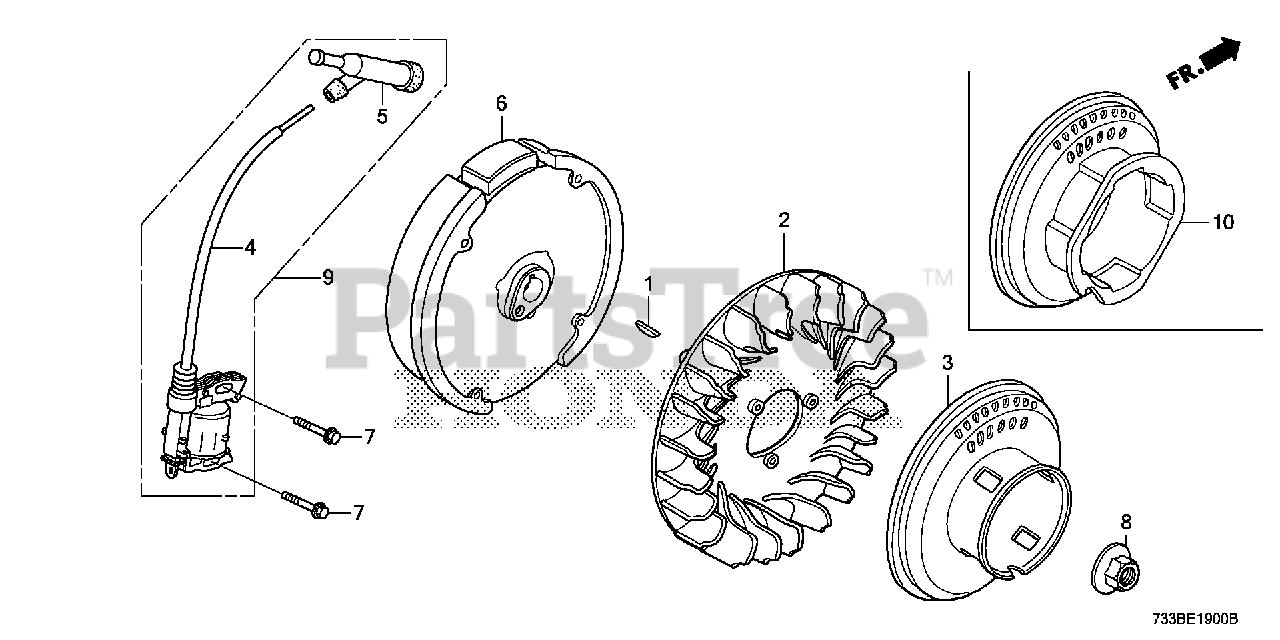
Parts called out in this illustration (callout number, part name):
1	KEY, SPECIAL WOODRUFF (25X18)
2	FAN, COOLING
3	PULLEY, STARTER
4	COIL ASSY., IGNITION
4	COIL ASSY., IGNITION (KOKUSAN)
5	CAP ASSY., NOISE SUPPRESSOR
5	CAP ASSY., NOISE SUPPRESSOR (KOKUSAN)
6	FLYWHEEL (YUXIN)
7	BOLT, FLANGE (6X25) (CT200)
8	NUT, SPECIAL (14MM)
